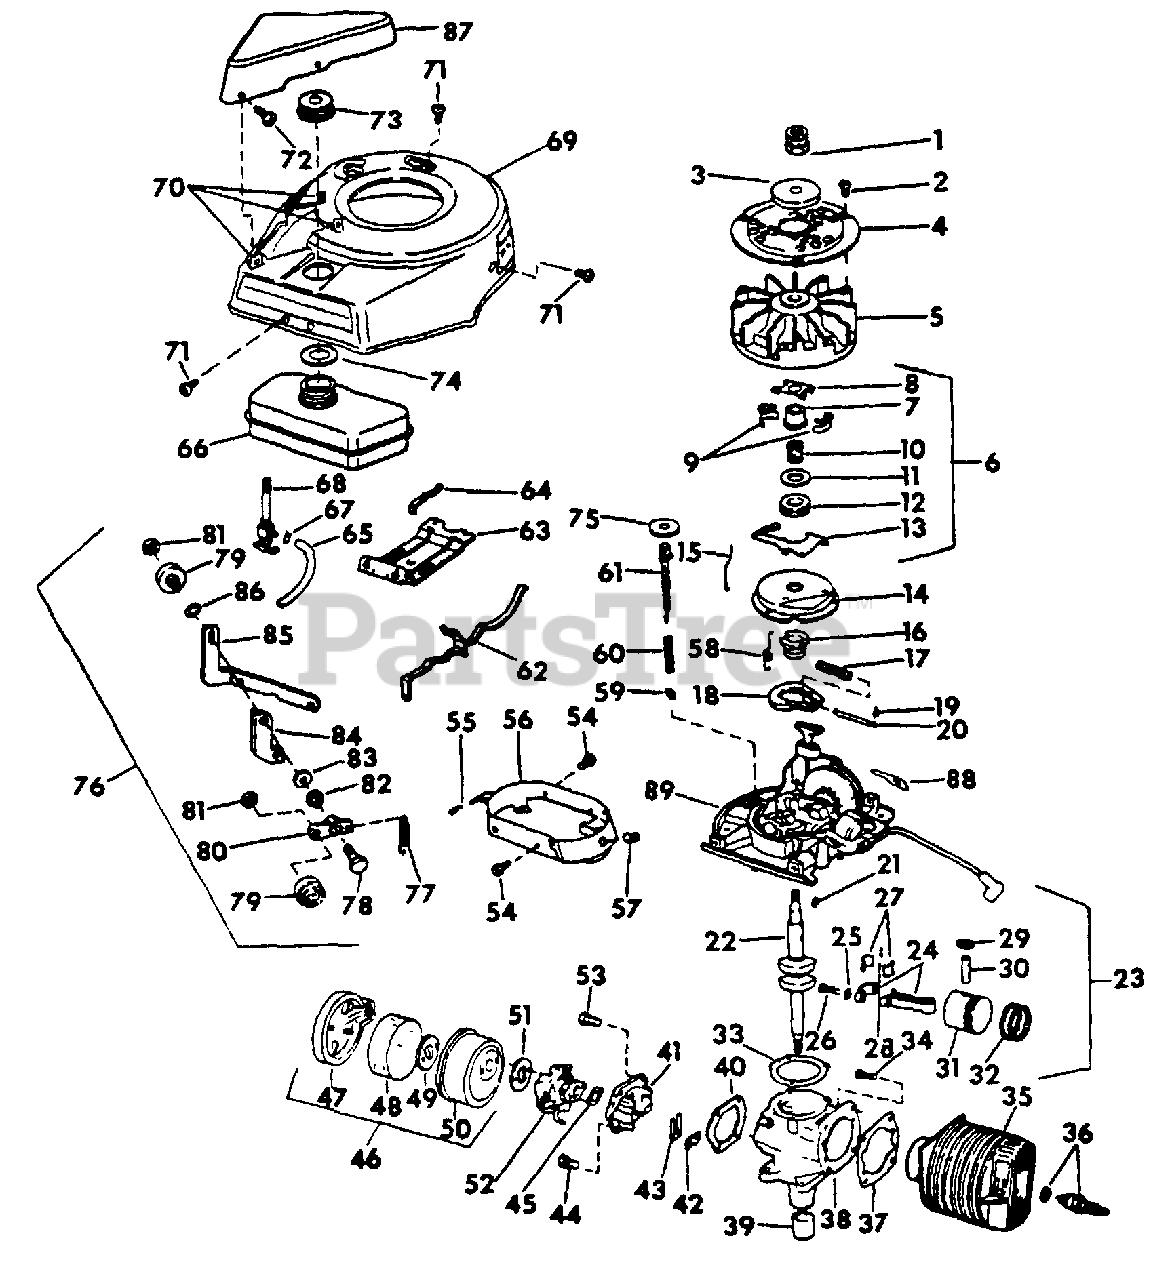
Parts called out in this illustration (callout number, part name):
1	PULLEY, DRIVE
2	SCREW, THD CUTTING
4	SCREEN FLYWHEEL
6	GOVERNOR ASSY
7	COLLAR, GOVERNOR
8	YOKE, GOVERNOR
9	WEIGHT, GOVERNOR
10	SPRING, GOVERNOR
11	WASHER, THRUST
12	COLLAR, THRUST
13	LEVER, GOVERNOR
15	ROD, GOVERNOR
16	CAM. SPARK ADVANCE
17	SPRING, SPARK ADVANCE
18	FLYWHEEL, SPARK ADVANCE
19	RETAINER, SPRING
20	PIN, SPARK ADVANCE
21	KEY, CRANKSHAFT
23	PISTON & CONNECTING ROD ASSY
24	ROD ASSY, CONNECTING
25	LOCKPLATE, SCREW
26	SCREW, CONNECTING ROD
27	LINER, CONNECTING ROD
28	BEARING SET, NEEDLE - PACKED
29	RING, RETAINING
32	RING SET, PISTON -2 RINGS
33	GASKET, CRANKCASE TO ARM PLATE .010
34	SCREW, CYL TO CRANKCASE
35	CYLINDER & SLEEVE
36	SPARK PLUG & GASKET
37	GASKET, CYL TO CRANKCASE
38	CRANKCASE & SEAL ASSY
40	GASKET, REED PLATE
41	REED PLATE ASSY
42	PLATE, BACKUP
44	SCREW, HH REED PLATE TO CRANKCASE
45	GASKET, CARBURETOR
46	FILTER ASSY, AIR
47	CAP - PAINTED WHITE
48	ELEMENT, AIR CHAMBER
50	CHAMBER, AIR - PAINTED WHITE
52	CARBURETOR ASSY
53	SCREW, HH REED PLATE TO CRANKCASE
54	SCREW, BAFFLE
55	NUT, COVER MTG
57	GROMMET COVER MTG
58	SPRING, VARIABLE SPEED
59	BLADE, SWITCH
60	SPRING, SHUTOFF SWITCH
61	BAR, SHUT-OFF & PRIMER
62	CONTROL & GUIDE, VARIABLE GUIDE
63	BRACKET, FUEL TANK
64	SPRING, FUEL TANK
66	FUEL TANK ASSY
67	CLAMP, HOSE
68	VALVE & SCREEN, SHUT-OFF
69	COVER ASSY, ENGINE
71	SCREW, COVER MTG
73	CAP, GAS TANK
74	GASKET, TANK TO SHROUD
75	NOT USED ON THIS APPLICATION
76	IDLER BRACKET PULLEY ASSY
78	BOLT, SHOULDER
79	PULLEY & BRG
81	NUT, CENTERLOCK
84	BRACKET, SPRING RETAINER
85	BRACKET, IDLER
87	COVER, BELT - PAINTED WHITE
89	MAGNETO ASSY
